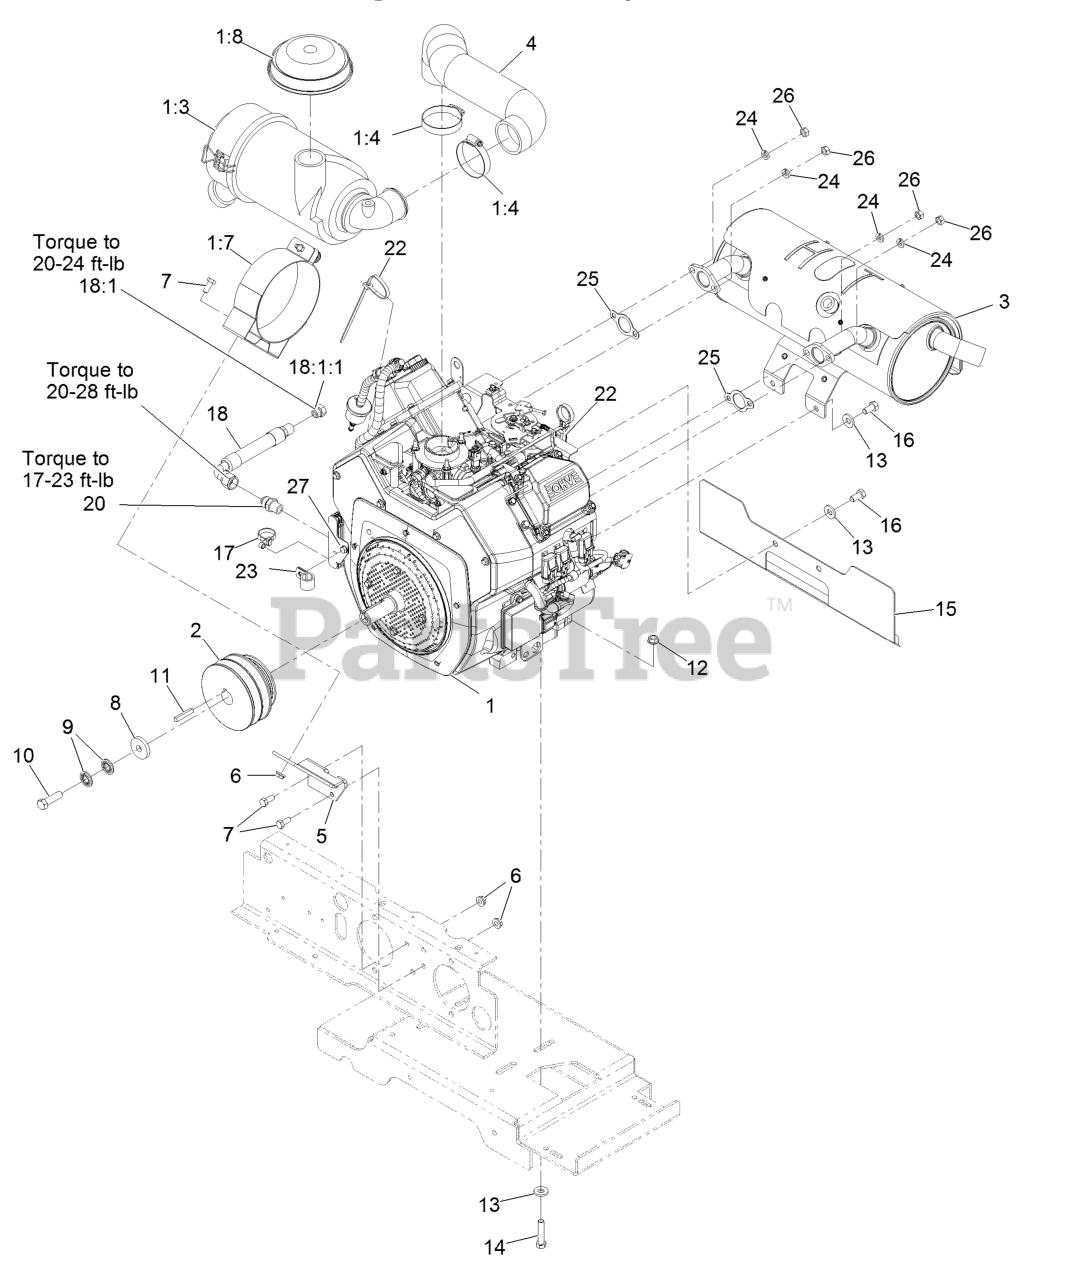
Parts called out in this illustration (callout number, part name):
1:3	AIR CLEANER CANISTER ASM
1:4	CLAMP-HOSE
1:7	BRACKET-FILTER, AIR
1:8	HOOD-CLEANER, 2" AIR INTA
4	HOSE-AIR INTAKE
5	BRACKET-FILTER, AIR
7	SCREW-HH
8	WASHER-CLUTCH
9	WASHER-SPRING
10	SCREW-HH
11	KEY-SQUARE
12	NUT-HHF, WHIZ
13	WASHER-BELLEVILLE
14	SCREW-HH
15	SHIELD-EXHAUST
16	SCREW-HH
17	Tie-Cable
18	OIL DRAIN HOSE ASM
18:1	PLUG-HH
18:1:1	O-RING
20	FITTING-STRAIGHT
22	TIE-PLASTIC
23	CLIP-LOOM
24	WASHER-LOCK
26	NUT-HEX
27	SCREW-HH
